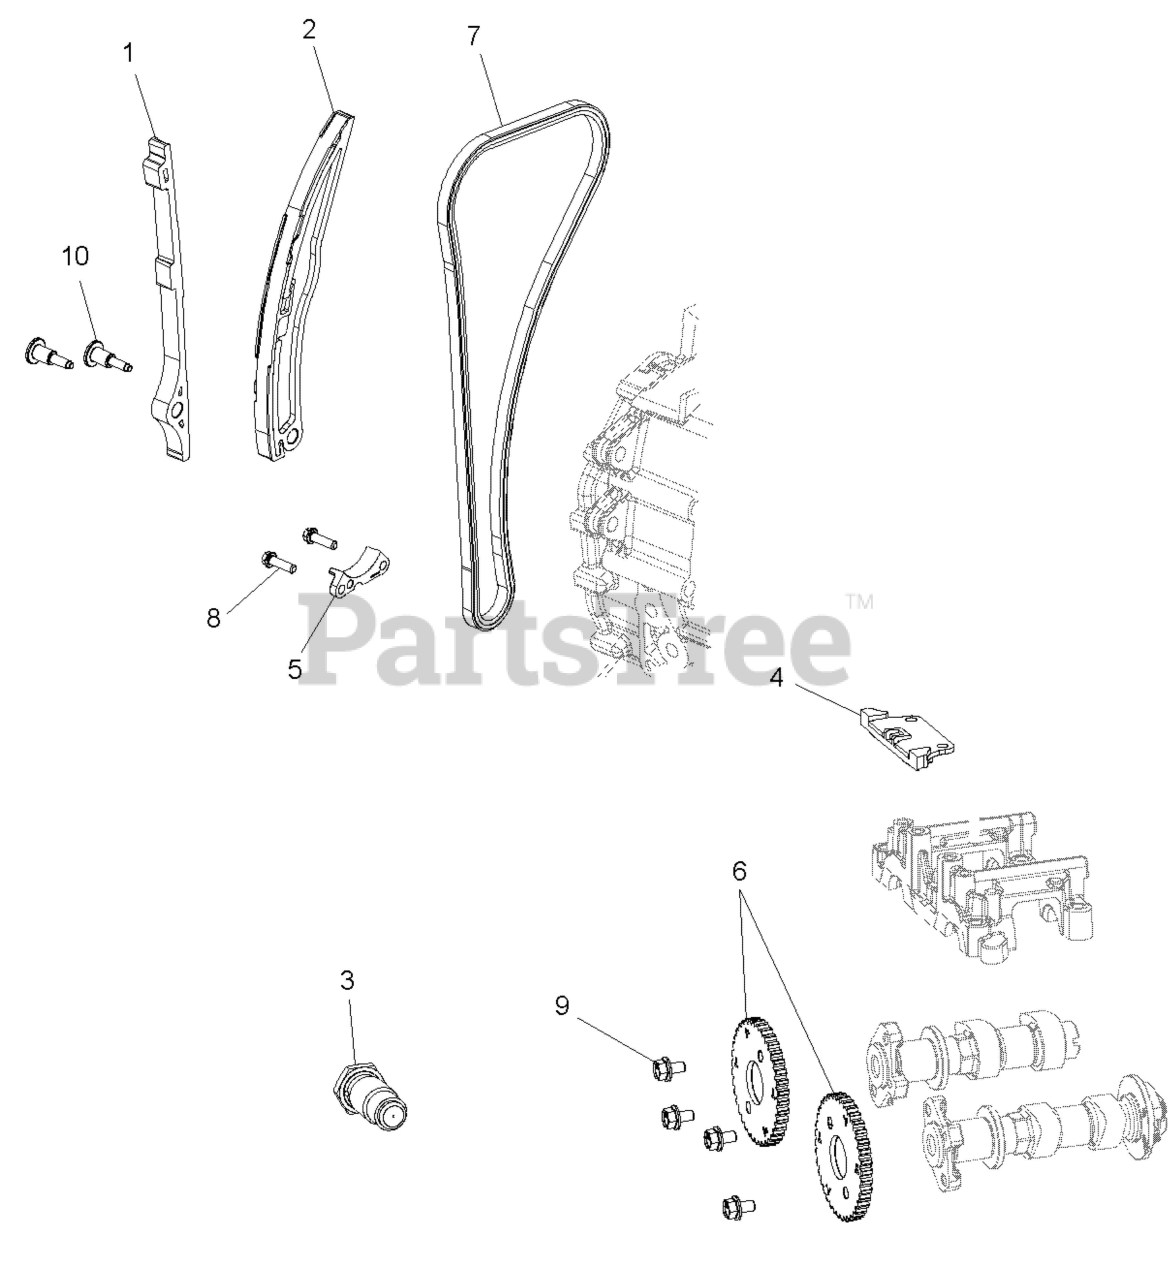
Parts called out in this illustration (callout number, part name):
1	GUIDE-CAMCHAIN,FIXED
2	GUIDE-CAMCHAIN,TENSIONER
3	TENSIONER-CAMCHAIN,HYD
3	GASKET-TENSIONER
4	GUIDE, CAMCHAIN, FIXED, COVER
5	GUIDE, CAM DRIVE, LOWER
6	SPROCKET, CAM, DRIVEN
7	CHAIN-CAMSHAFT 144L
8	SCR-M6X20,HXFLG,0600214
9	SCR-HXFL,M6X1.0X10 10.9
10	BOLT-SHLDR,M6X12X15
